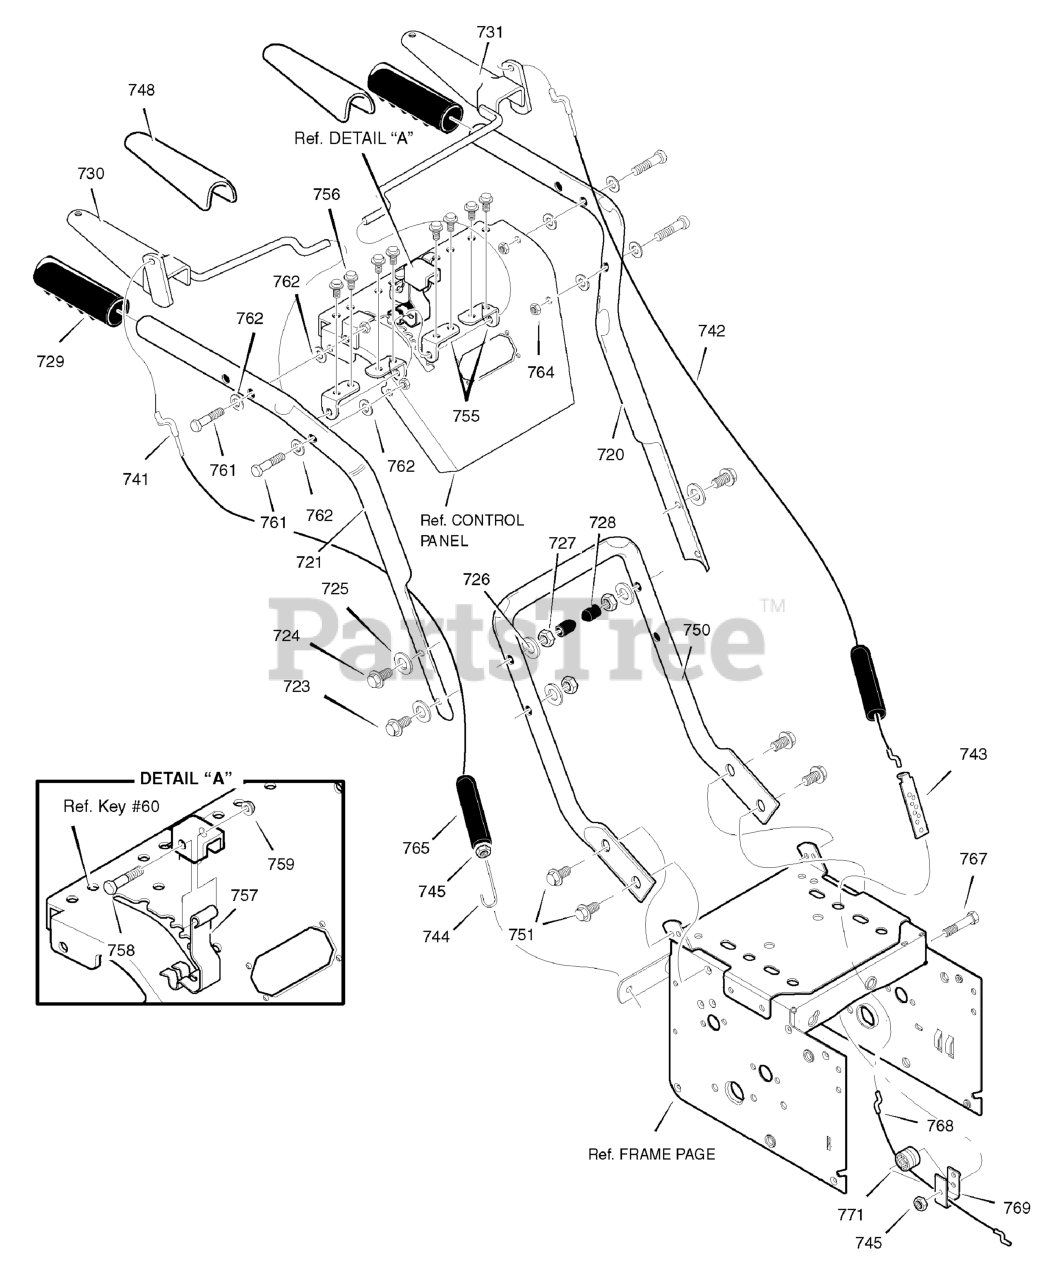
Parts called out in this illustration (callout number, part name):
720	HANDLE, UPPER LH
721	HANDLE, UPPER RH
723	SCREW
724	SCREW
725	WASHER, Flat, 13/32
726	WASHER
727	NUT, REGHEX
728	STOP, PLASTIC
729	GRIP-HANDLE
730	LEVER, ASSEMBLY CLUTCH DRIVE RH
731	LEVER, ASSEMBLY CLUTCH DRIVE LH
741	CABLE, AUGER CLUTCH
742	CABLE, AUGER DRIVE
743	BRACKET, CABLE ADJUSTER
744	SPRING, AUGER CLUTCH
745	NUT, 1/4-20
748	GRIP, CLUTCH HANDLE
750	HANDLE, LOWER
751	SCREW
756	SCREW
757	SPRING, CAM LOCK
758	BOLT, HEX
759	NUT
761	SCREW
762	WASHER, FLAT
764	NUT, HEX
765	BOOT, CLUTCH SPRING
767	BOLT, HEX 1/4-20 X 1.50
768	CABLE, LOWER DRIVE 12"
769	BRACKET, CABLE SPOOL YZ
771	SPOOL-CABLE, AUGER CLUTCH
